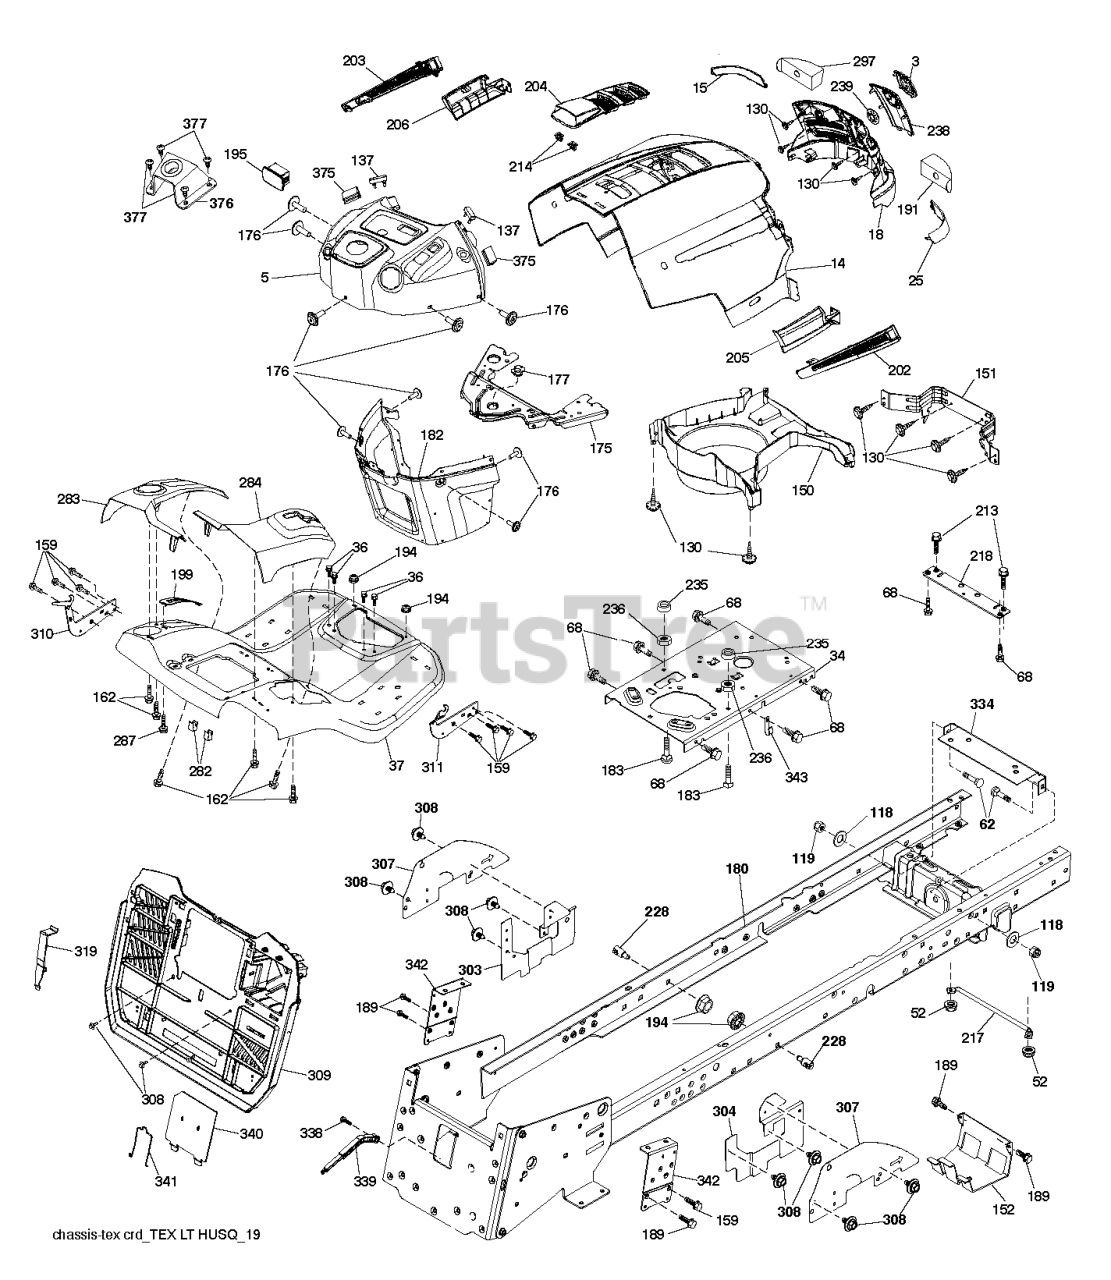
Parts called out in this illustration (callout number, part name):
3	LOGO.HUSQ.GT.LT.CROWN.H
5	DASH.UPPER.HUSQ LT CABLE.CLUTC
14	HOOD.HUSQVARNA.LT.ORANGE
15	LENS.HUSQVARNA LT.RH
18	GRILLE.SVC.HUSQVARNA.GREY
25	LENS.HUSQVARNA LT.RH
34	PLATE.ENGINE.10GA.CRD.GENII
36	SCREW 5/16"
37	FENDER.TEX.SRD.CRD.FRN.GUARDS
52	LOCKNUT
62	BOLT D
68	SCR 5/16-18 X 1/2 SELFTAP ZN
118	WASHER
130	SCREW.#10 X 0.750.BOS
137	BUMPER DASH
151	BRACKET PIVOT
152	SHIELD.BROWNING.W/TEX
162	SCREW.HI-LO.CONSOLE
175	CROSSMEMBER
176	SCREW.#10-24X5/8.RN.QU
177	BUSHING STEERING
180	CHASSIS WLDT TEX CRD
182	DASH.LOWER.PREDATOR LT
183	BOLT.5/16-18X1-1/4 FULL THD
189	SCREW
191	INSERT.REFLECTIVE.RH.
194	NUT LOCK HEX FLANGE 5/16-18
195	PLUG.TEX.DASH.SVC.MINDER.GREY
199	PLATE DECK LIFT
202	VENT.SIDE.HUSQVARNA.LT.RT
203	VENT.SIDE.HUSQVARNA.LT.LFT
204	SUBASM.TOP.VENT.HUSQ.LT
205	SKIRT.SIDE.HUSQVARNA.LT.RT
206	SKIRT.SIDE.HUSQVARNA.LT.LEFT
213	BOLT
214	CLIP.RETAINER.TINNER.
217	ROD.PIVOT.HOOD
218	X-PIECE.HOOD.STOP.NON/
228	STUD.FASTNER.W/ANTI-ROTATE
235	SPACER FENDER
236	NUT.CENTERLOCK.5/16-
238	TRIM.HUSQ LT.668
282	CLIP.RETAINER.CONSOLE.LT.HUSQ
283	CONSL.DECKLIFT.LH.SRD.TEX.CRD
284	CONSL.SHFT.PEDAL.RH.SRD.TEXCRD
287	SCREW 1/4X20
297	INSERT REFLECTIVE
303	SHIELD.LWR.LH.LT.30"CRDSRD.PNT
304	SHIELD ISO RH LOWER CRD GEN 1
307	SHIELD.UPPER.CRD.SRD.ISO
308	BOLT.5/16-18UNCX3/4 W/SEMS.BLK
309	BACKPLATE.TEX.CRD.GEN.1
310	LH.ADJUST.HANGER.BRACKET.ASM
311	RH.ADJUST.HANGER.BRACKET.ASM
319	BRACKET.ACTUATOR.BAGGER.SRD
334	BRACKET.ENGINE
338	BOLT BOLT SHOULDER
339	LEVER LEVER BAGGER
340	DOOR.PNT.BATTERY.TRY.TEX.CRD.
341	LATCH.BATTERY.DOOR.TCRD
342	SUPPORT.PNT.FENDER.CRD.TEX
343	CLIP CLIP
375	BUMPER CLIP-ON. DASH 1"
376	MOUNT.ASM.HUSLT.UPPER.STRNG
377	SCREW 10 X 1/2 ZN PL PHIL PAN
